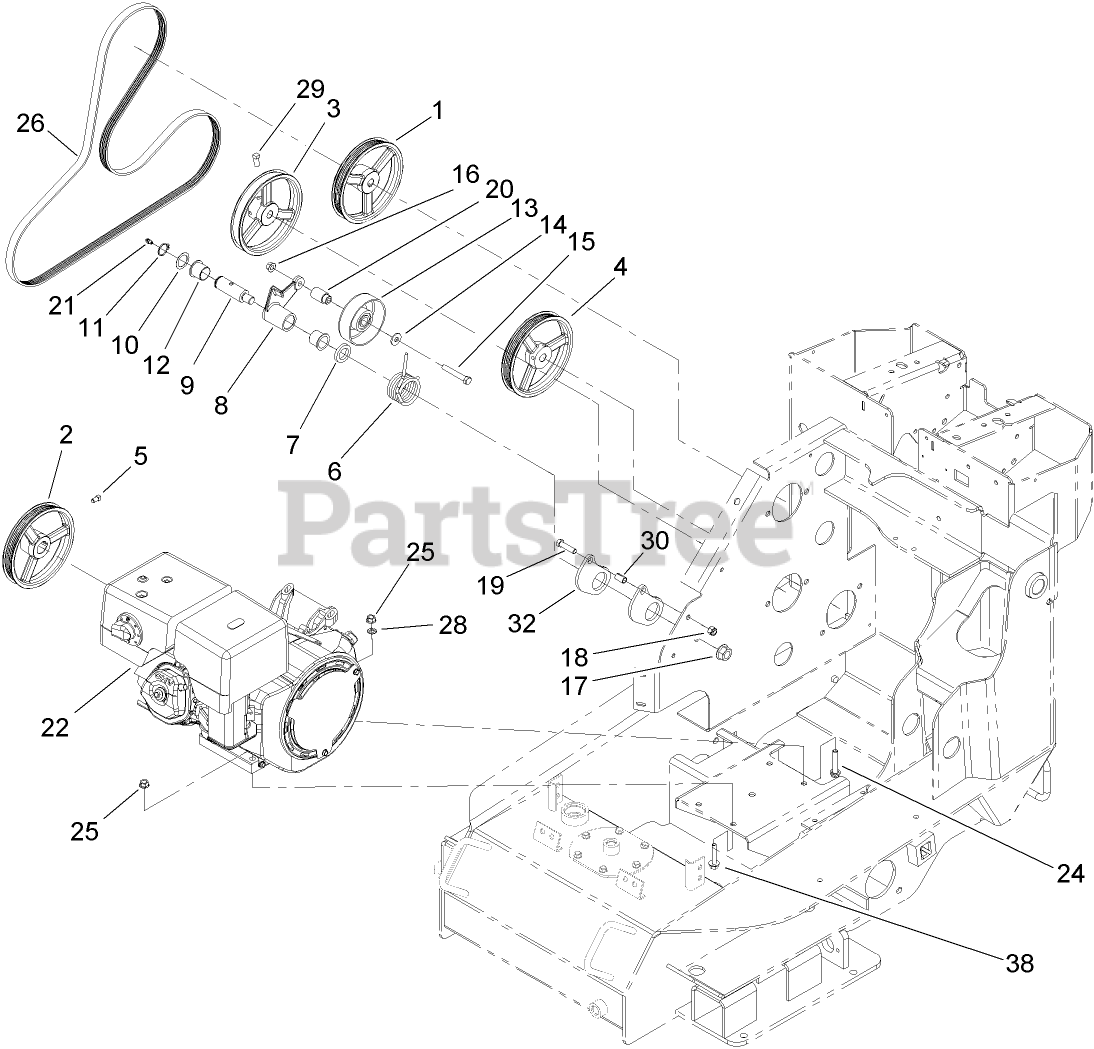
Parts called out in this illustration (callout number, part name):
1	PULLEY
2	PULLEY
3	PULLEY
4	PULLEY
5	SCREW-SQH
6	SPRING-TORSION
7	SPACER-ARM, IDLER
8	ARM-IDLER
9	SHAFT-PIVOT, IDLER
10	WASHER
11	RING-RETAINING
12	BUSHING-FLANGE
13	PULLEY-IDLER
14	WASHER-HARDENED
15	SCREW-HH
16	NUT-HF
17	NUT-HF
18	NUT-LOCK, NI
19	SCREW-HH
20	SPACER-IDLER
21	FITTING-GREASE
24	SCREW-HHF
25	NUT-HF
26	BELT-POLY-V
28	WASHER-LOCK
29	SCREW-SET, SQH
30	SPACER-SCRAPER, STOP
32	PAD-RUBBER
38	SCREW-HHF, WHIZ
